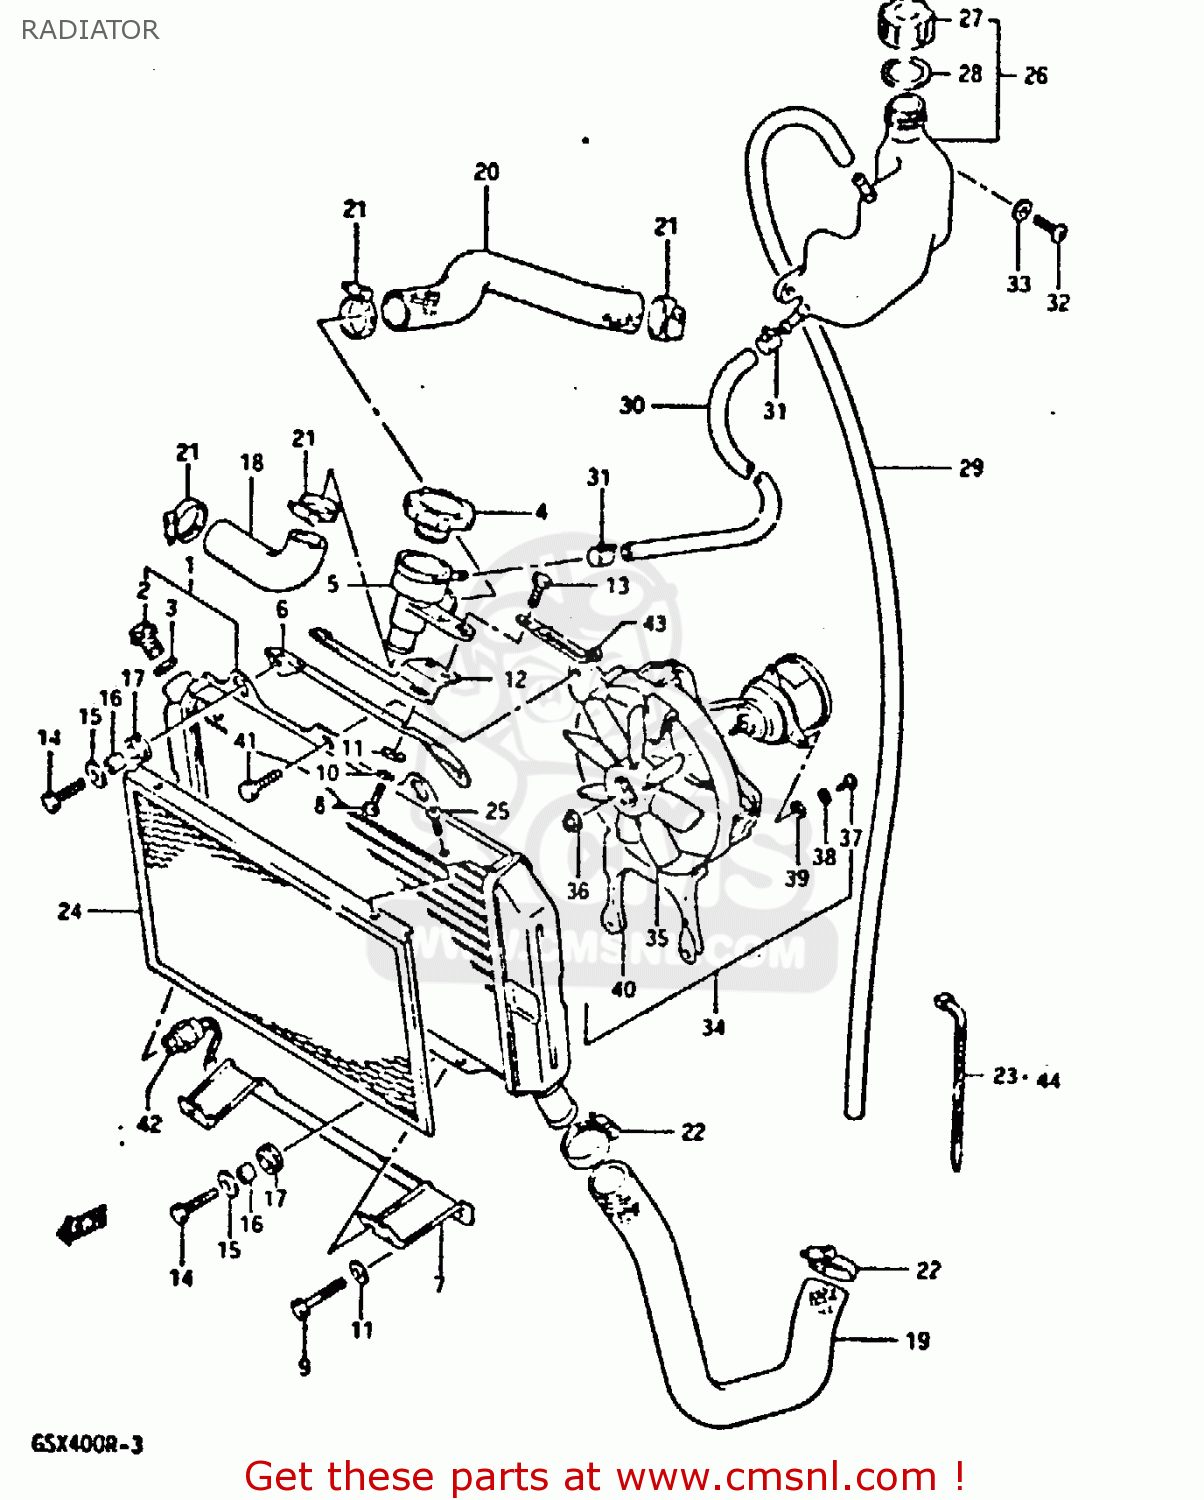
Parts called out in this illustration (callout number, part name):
2	PLUG
3	GASKET
4	CAP,RADIATOR 1.1
5	CONDUCTION
7	BRACKET
8	BOLT
9	BOLT
10	WASHER,LOCK
11	WASHER
13	BOLT 6X12
14	BOLT
15	WASHER (6.5X18X1.6)
16	SPACER (6.8X10X10)
17	CUSHION
18	HOSE,RADIATOR INLET
21	CLAMP
22	CLAMP
23	CLAMP(L:165)
24	RADIATOR NET
25	SCREW
26	RESERVOIR TANK
27	CAP,RESERVOIR TANK
28	GASKET,RESERVOIR TANK CAP (NAS)
29	HOSE
30	HOSE
31	CLIP
32	SCREW
33	WASHER
34	RADIATOR FAN
35	FAN ASSY
36	NUT 5MM
37	SCREW
38	LOCK WASHER
39	WASHER
40	SHROUD
41	BOLT
42	SWITCH,RADIATOR FAN
43	CLAMP
44	CLAMP(L:95)
